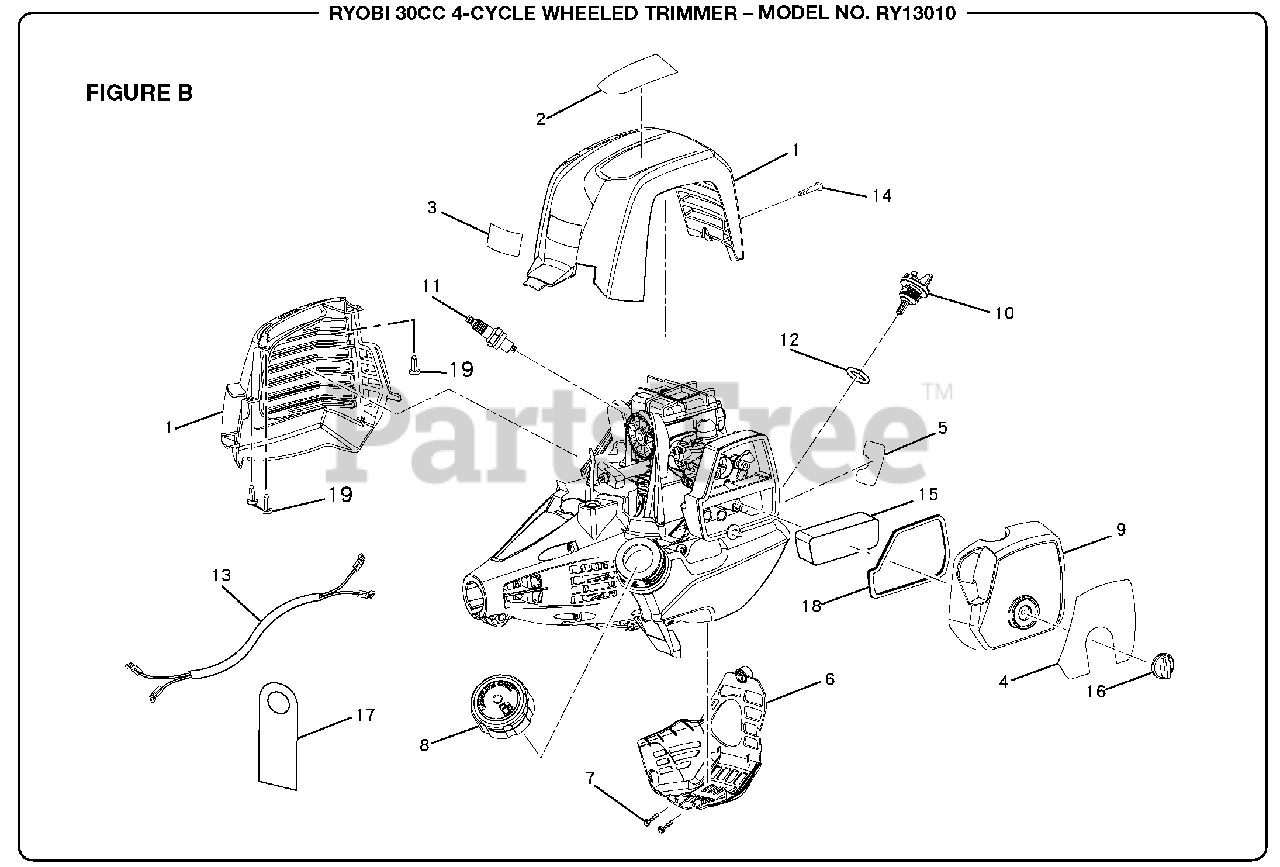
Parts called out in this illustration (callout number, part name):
1	Top Cover Assembly
2	Label (RY13010)
3	Logo Label
4	Starting Label
5	Hot Surface Label
6	Bottom Cover
7	Screw (M6-19 x 1/2 in.)
8	Fuel Cap Assembly
9	Air Box Cover
10	Oil Cap/Dipstick
11	Spark Plug (Champion RZTC)
13	Wiring Harness
14	Screw (M5 x 20 mm)
15	Air Filter
16	Air Cover Knob
19	Screw (M4 x 12 mm)
